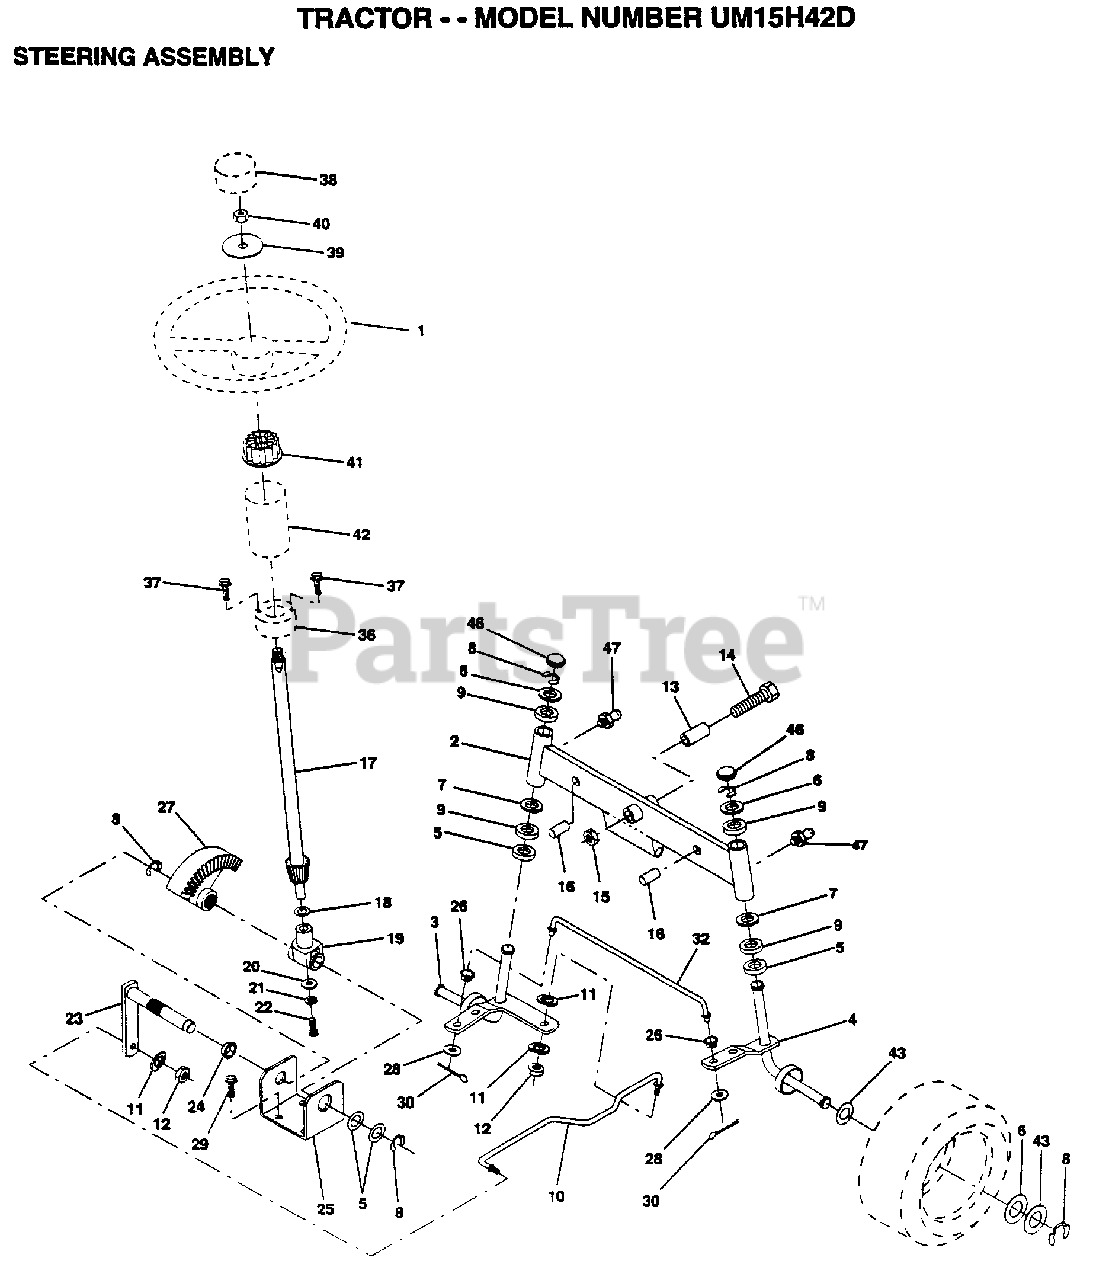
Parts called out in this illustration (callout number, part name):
2	AXLE ASM FRONT
3	SPINDLE LH
4	SPINDLE RH
5	WASHER .T
6	WASHER
7	WASHER
8	RING
9	COL. SRTG. BEAR.
11	LOCKWASHER
13	BEARING
14	BOLT HEX 5/8-11
15	"NUT-LOC,FLANGE LT"
16	AXLE PIN
17	SHAFT ASM
18	THRUST WASHER
19	SUPPORT.SHAFT
21	LOCKWASHER
22	"SCREW,SPECIAL"
24	NYLINER T
25	"BRKT,STEERING"
26	BUSHING.DRAGLINK
27	GEAR SECTOR
28	WASHER
29	SCREW
30	COTTER PIN
32	TIE ROD
38	ST WHL INSERT CAP
39	WASHER T
40	GRIPCO NUT
41	ADAPTER-WHEEL LT
42	"TUBE, STR SHAFT"
43	WASHER
46	CAP
47	ZERK M
